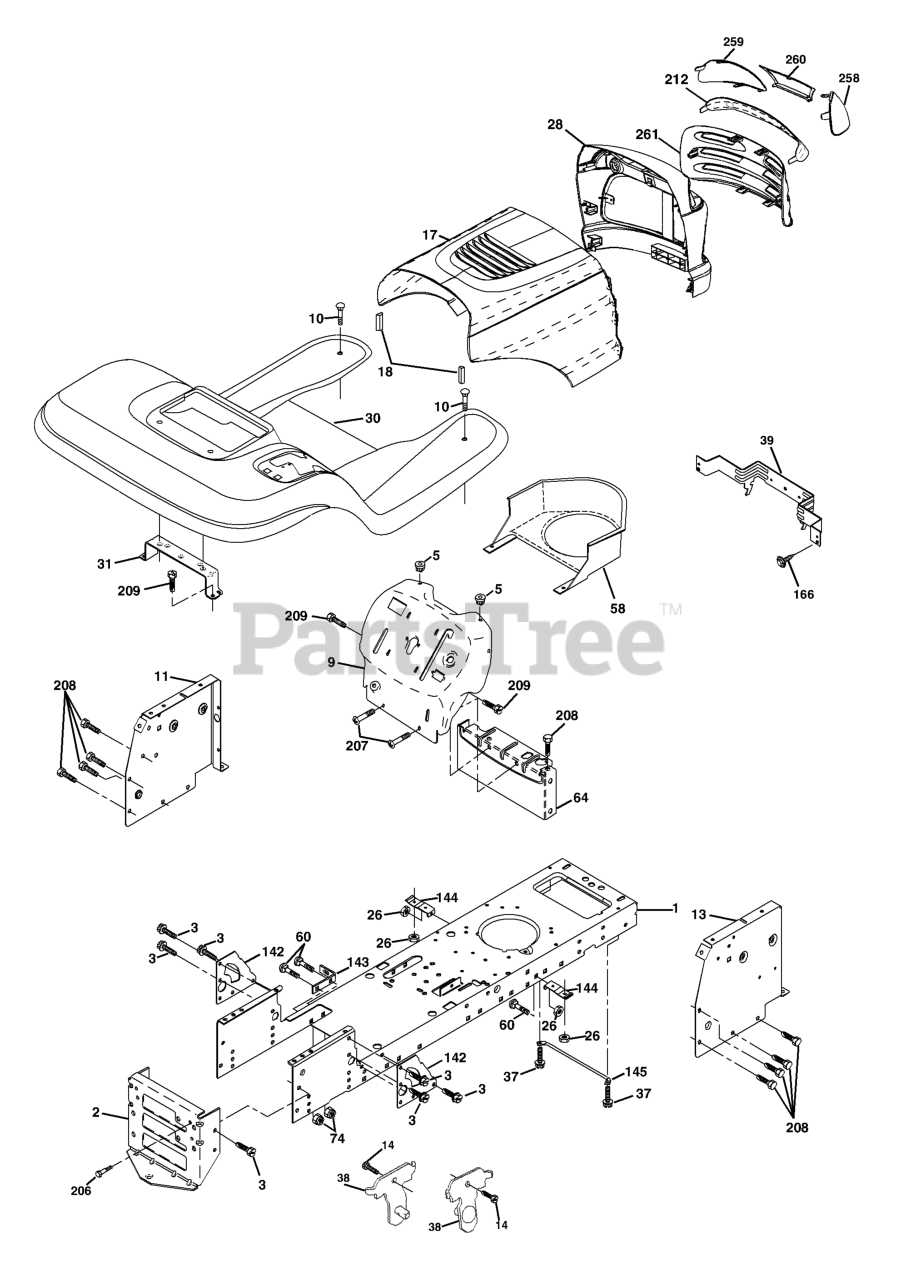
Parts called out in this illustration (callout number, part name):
1	CHASSIS STAMPING
2	DRAWBAR, 12GA
3	SCREW 3/8-16X3/4
5	BUMPER.RUBBER.HOOD
9	DASH
10	BOLT D
11	PANEL.DASH.LH.LTX
13	PANEL DASH RH
14	SCREW LT
17	HOOD
18	BUMPER.HOOD.LARGE.1.75"
26	NUT
28	GRILL/LEN.ASM.DL.HUSQ
30	FENDER FOOTREST
31	BRACKET.SUPPORT.FENDER
37	Screw Thdrol 5/16-18 x 1/2
38	BRACKET.ASM.PIVOT.MOWER.REAR
39	BRACKET PIVOT LASER
58	AIR DUCT P/L/LT
60	Bolt RDHD SQNK 3/8-16 x 3/4
64	DASH LOWER
142	PLATE REINFORCEMENT
143	BRACKET, SWAY BAR
144	BRKT, FOOT REST
145	ROD PIVOT CHASSIS/HOOD
166	SCREW
206	SHOULDER BOLT 5/16-18TT
207	SCREW, 5/16-18 X 1/2
208	SCREW 3/8-16X1/2
209	SCREW, 3/8-16X3/4
212	INSERT.LENS.REFLECTIVE
258	LENS LH
259	LENS LH
260	COVER.LENS.HUSQ.( HAVE GRAY)
261	INSERT GRILLE
